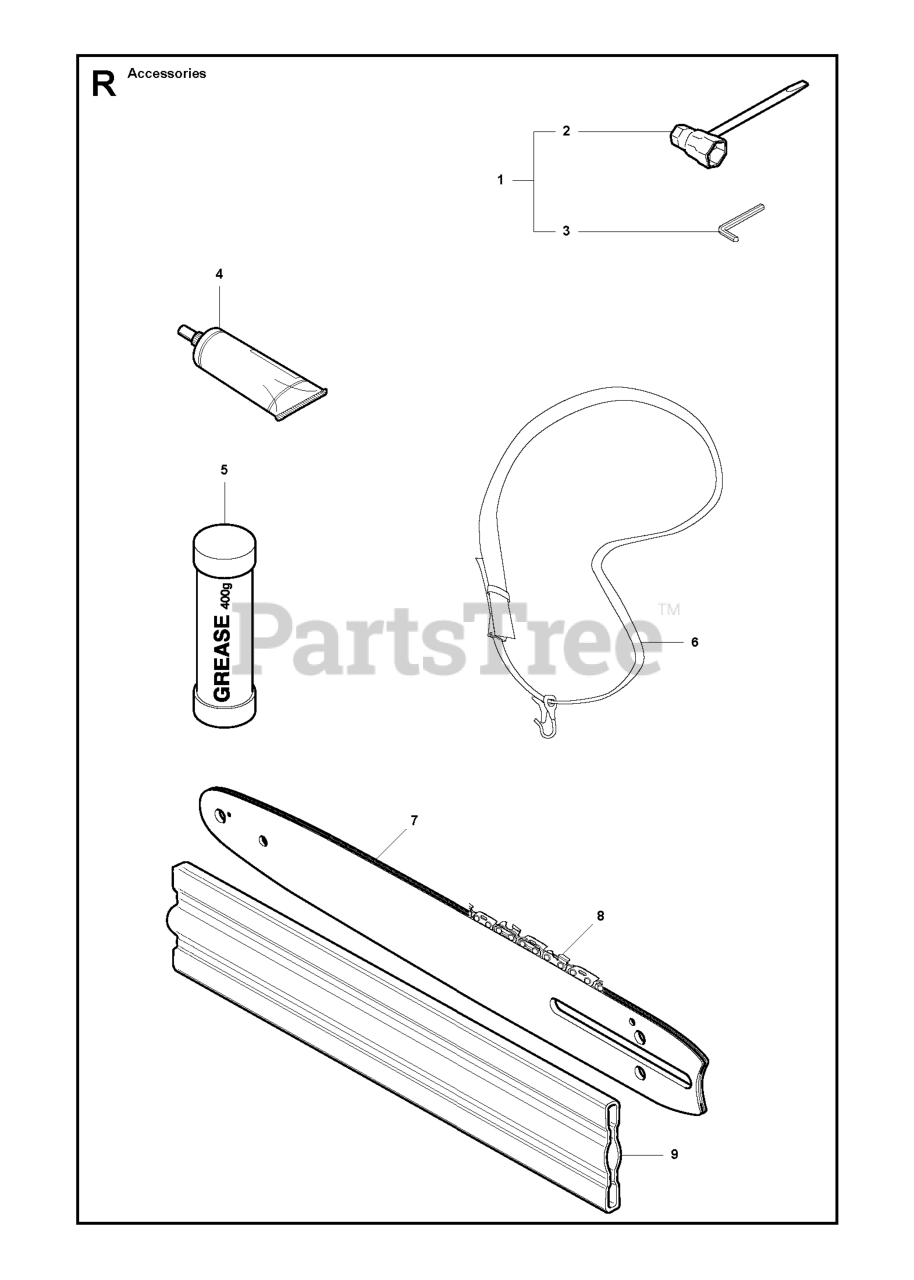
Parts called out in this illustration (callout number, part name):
1	ACCESSORY KIT
2	COMBI TOOL
3	L-KEY WRENCH
4	GEAR GREASE -1 TUBE
5	Grease 400 Grams
6	Harness - Diagonal with sign
6	Harness-w/o warning
7	Hl280-45 Guide Bar
7	Hl280-40 Guide Bar
8	Chains 36(91vg)4se
8	Chain Loop S36
